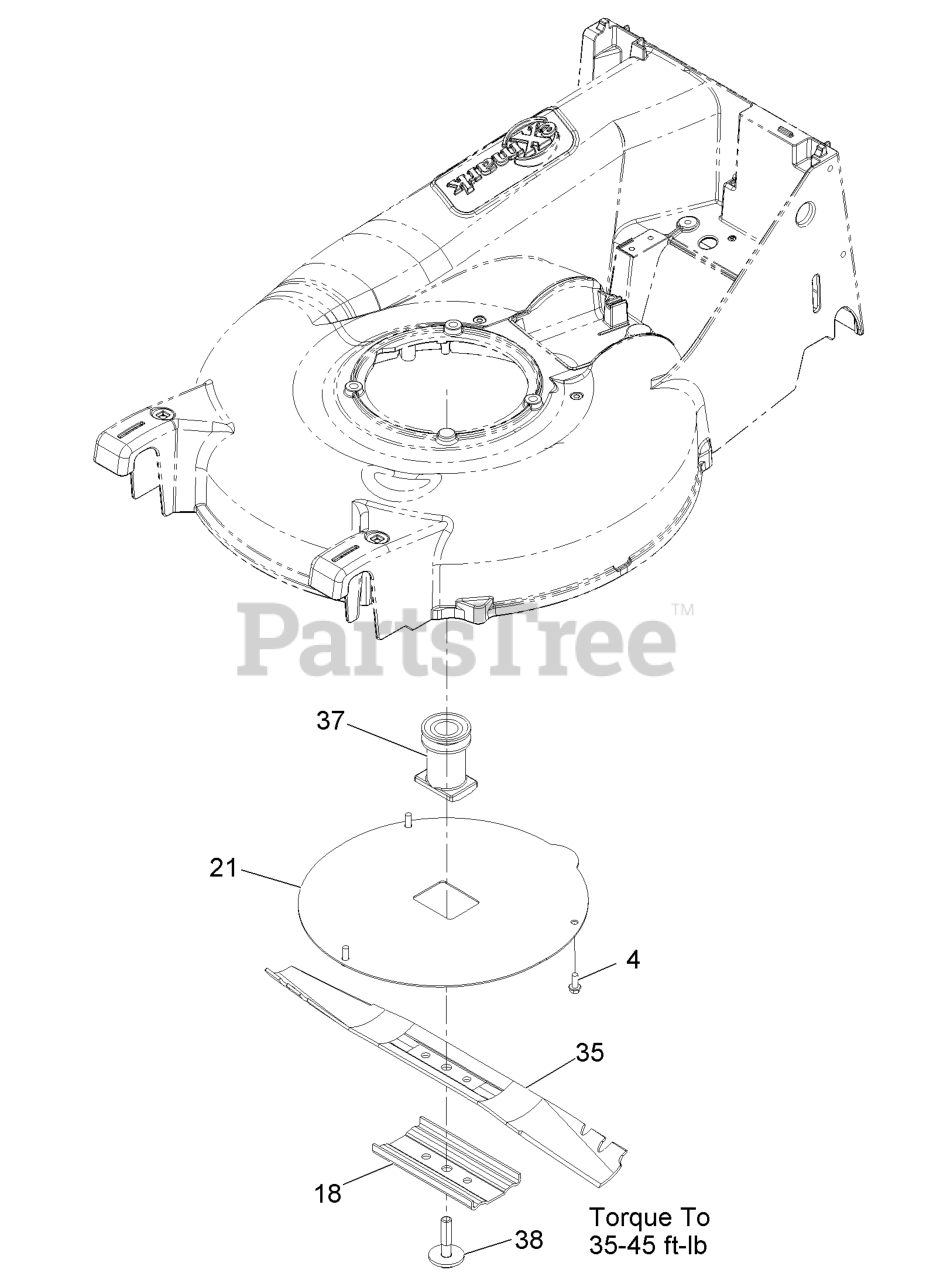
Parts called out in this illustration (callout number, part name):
4	SCREW-HWH
18	SUPPORT-BLADE
37	BLADE-ADAPTER
38	BOLT-BLADE, SEM
